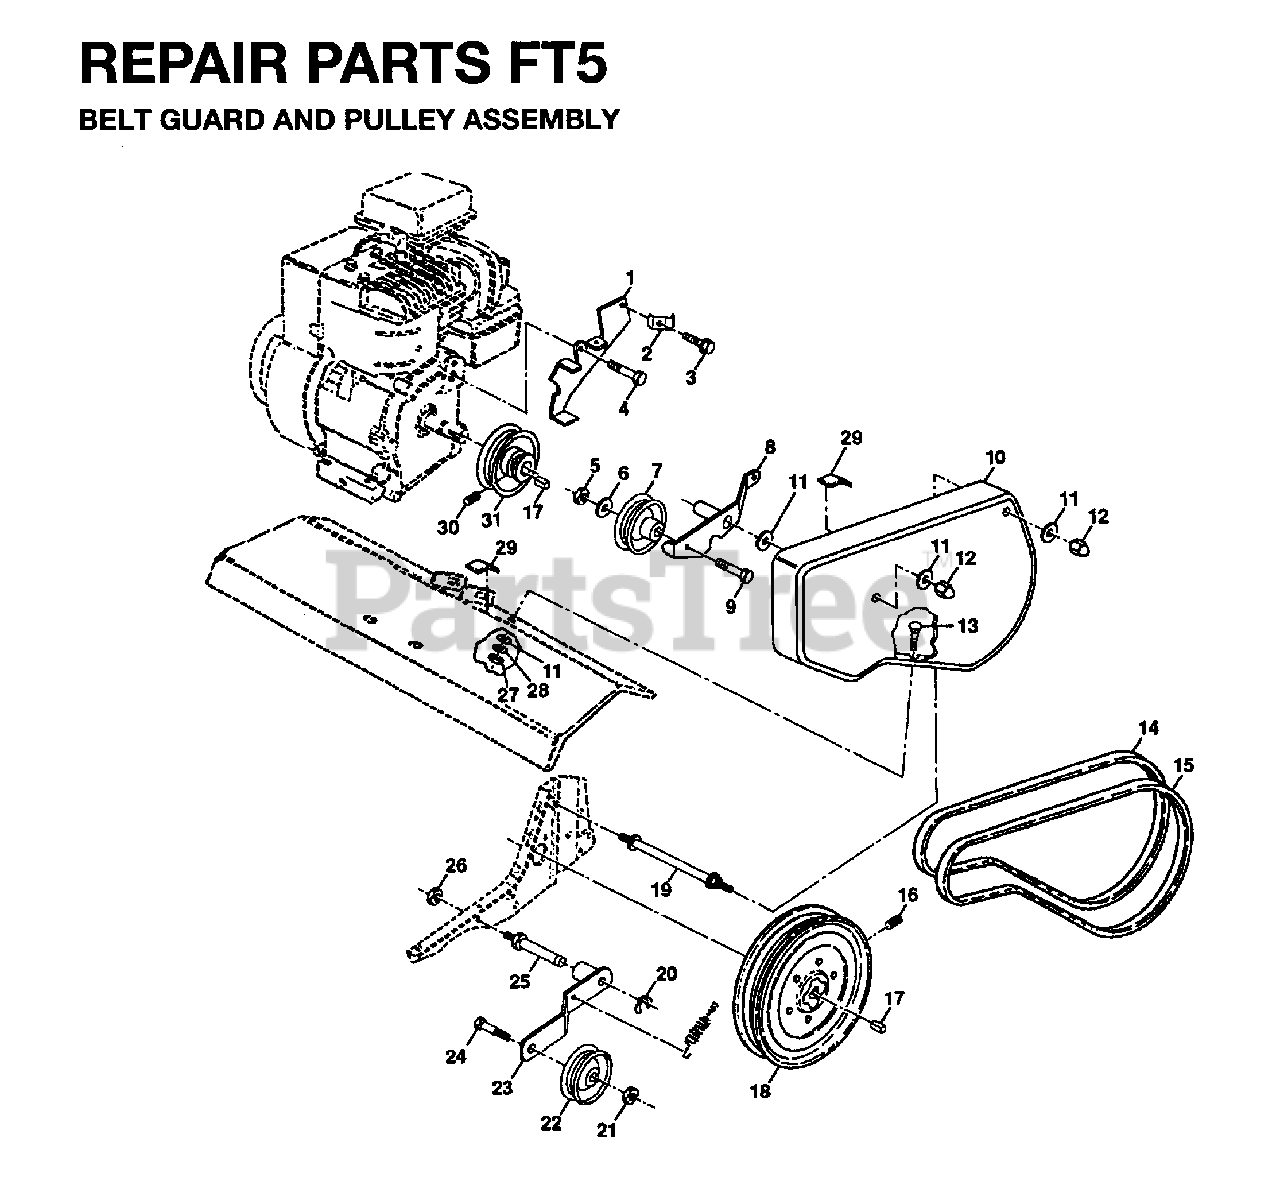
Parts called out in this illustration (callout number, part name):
2	CONDUIT CLIP T
5	NUT.HEX.3/8-16UNC
6	WASHER
7	PULLEY
9	BOLT
12	CAP
14	BELT
15	BELT
16	SET SCREW **
20	KLIP RING TI
21	NUT.HEX.3/8-16UNC
22	FLAT IDLER
24	BOLT
25	SHAFT.IDLER.TILLER
27	NUT
28	LOCKWASHER
29	PAD IDLER TI
